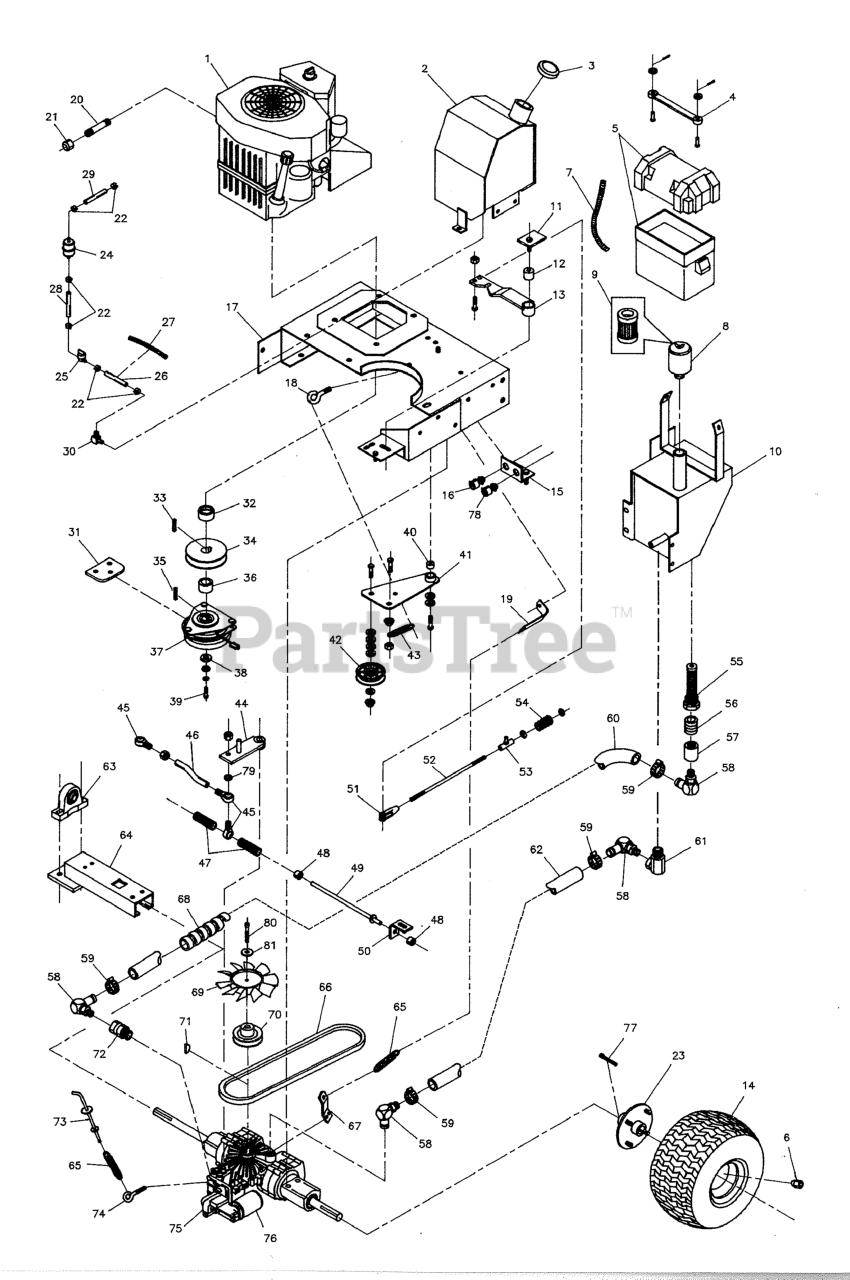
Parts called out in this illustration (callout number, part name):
2	Fuel Tank Weldment
4	RUBBER STRAP
5	BOX, Battery
6	LUG NUT, 1/2-20
7	WIRE LOOM, 17"
8	Air Filter Assembly
9	Air Filter Element
10	Oil Reservior Weldment
11	Bolt Plate Weldment
12	SPACER, .32 x .75 x 1.06
13	Neutral Lockout Weldment
14	WHEEL & TIRE ASSEMBLY, 20 x 10 x 8, Complete
15	Switch Plate Weldment
16	SWITCH, Plunger, NO
17	Engine Deck Weldment
18	EYEBOLT, 5/16-18 x 3-1/4
19	Brake Spring Holder
20	NIPPLE, 3/8 NPT X 4-1/2
21	CAP, 3/8 NPT
22	CLAMP, Hose
23	DRIVE HUB DETAIL
24	FUEL FILTER
25	VALVE, Fuel Shut-Off
26	1/4" Fuel Line, 19" Long
27	WIRE LOOM, 17"
28	1/4" Fuel Line, 6" Long
29	HOSE, 1/4" FUEL, 9.00"
30	Brass Fitting
31	CLUTCH ANCHOR PAD
32	SPACER, 1.13 X 1.75 X .88
33	KEY, 1/4" SQ. X 1-1/4
34	PULLEY, Crankshaft
35	KEY, 1/4 SQ. X 1
36	SPACER, 1.13 X 2.00 X .37
37	CLUTCH, Electric, 1-1/8" Shaft
38	SPACER, .45 x 1.62 x .37
39	CRANKSHAFT BOLT, 7/16 x 3
40	SPACER, .32 x .75 x 1.06
41	IDLER ARM ASSEMBLY, Complete
42	IDLER PULLEY
43	SPRING, Extension
44	Control Lever Weldment
45	BALL JOINT, 3/8-24 Male
46	Lock-Out Linkage Tube
47	SPRING, Compression
48	COLLAR, 5/16" Set
49	Linkage Weldment
50	Neutral Adjusting Bracket
51	CLEVIS, 5/16-24, Plastic
52	Linkage Rod
53	Brake Tube Weldment
54	KNOB
55	STRAINER
56	NIPPLE, 1/2" NPT Close
57	COUPLER, 1/2" NPT
58	FITTING, 90 Degrees 1/2" NPT
59	CLAMP, #10 Hose
60	Hydraulic Hose 16 1/2"
61	FITTING, 1/2 NPT Swivel, 90 Deg.
62	Hydraulic Hose 8 1/2"
63	BEARING, PILLOW BLOCK, 1
64	AXLE SUPPORT
65	SPRING, Extension
67	BRAKE LEVER
68	PROTECTIVE COIL, 13"
70	PULLEY, Transmission Input
71	KEY, #61 Woodruff
72	FITTING, 7/8" O-Ring Straight Swivel
73	Dump Valve Weldment
74	EYEBOLT, 1/4-20 x 2-1/2
75	Transmission
76	FILTER, Transmission Oil
77	Drive Axle Key
78	SWITCH, Plunger, NC
79	WASHER
80	BOLT, Allen Head, 1/4-20 x 1-3/4
81	WASHER, .265 x 1.50 x .109
